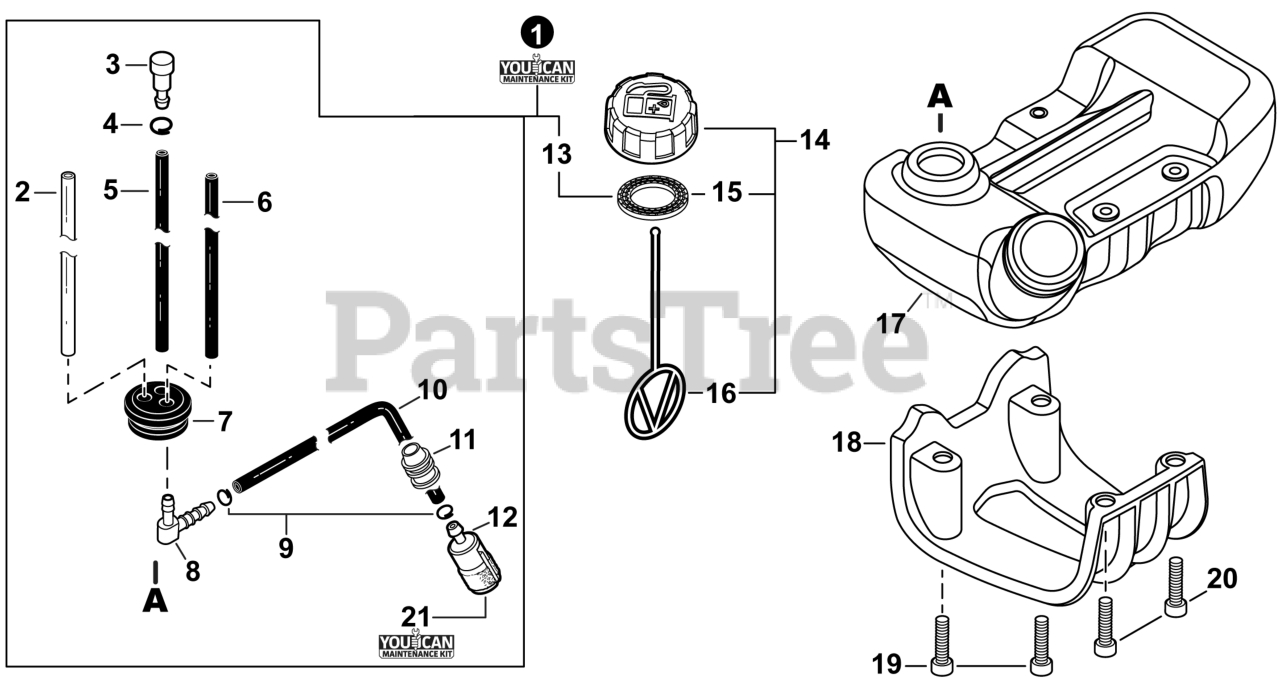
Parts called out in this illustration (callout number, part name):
1	FUEL SYSTEM KIT - YOUCAN™
2	PIPE, FUEL 3x6x85 YELLOW
3	VENT ASSY
4	CLIP 6.5 MM
5	PIPE, FUEL 3x6x95 BLACK
6	PIPE, FUEL 3x5.5x70 BLACK
7	GROMMET, FUEL
8	CONNECTOR, PIPE
9	CLIP 6
10	PIPE, FUEL 3x5x140x35 BLACK
11	BOOT
12	FILTER, FUEL
13	GASKET, FUEL CAP
14	CAP ASSY, FUEL
15	GASKET, FUEL CAP
16	CONNECTOR, CAP L= 123
17	TANK, FUEL
18	GUARD, FUEL TANK
19	BOLT, TORX 5x25
20	BOLT, TORX 5x20
21	TUNE-UP KIT - YOUCAN™
